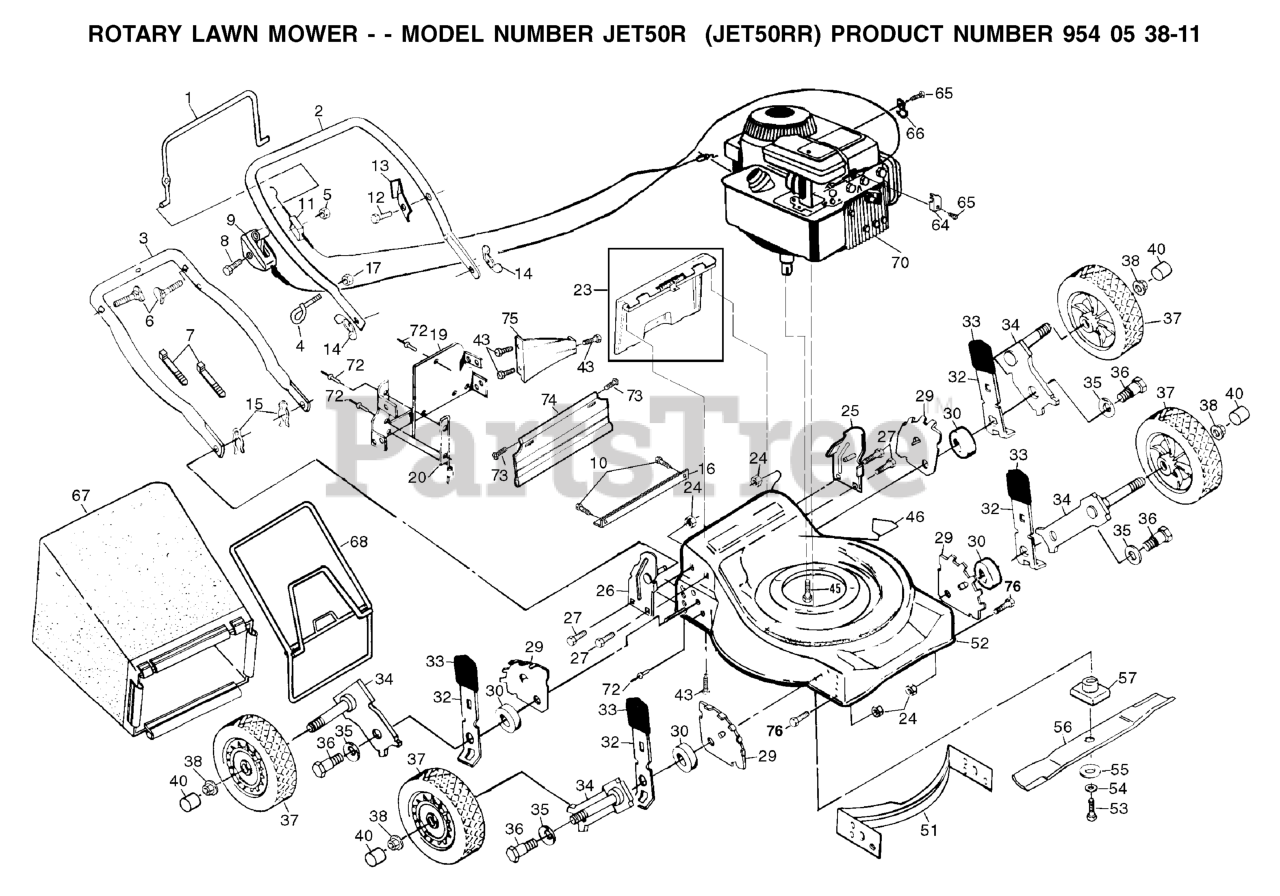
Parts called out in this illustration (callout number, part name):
1	CONTROL BAR
2	UPPER HANDLE
3	HANDLE
4	ROPE, GUIDE
5	NUT
6	HANDLE BOLT
7	TIE GUIDE
8	SCREW.PAN.HEAD
9	THROTTLE CONTROL
11	CABLE.MZR.51.RT.SP./PU.
12	TAPPING SCREW
13	BRACKET UPSTOP
14	NUT WING PM
15	HAIRPIN COTTER
16	REPL BY 532 14 61-43
17	NUT
20	SIDE BAFFLE
23	REAR DOOR ASSEMBLY KIT
24	LOCKNUT PM
25	HANDLE BRACKET ASSEMBLY - LEFT
26	HANDLE BRACKET ASSEMBLY-RIGHT
27	SELF-TAPPING SCREW 5/16-18X3/4
29	WHEEL ADJUST BRACKET
30	RP SPACER HT ADJ
32	SELECTOR SPRING
34	AXLE, REAR
35	WASHER.BELLEVILLE (3 2 LB)
36	BOLT
37	WHEEL
38	HEX FLANGE LOCKNT
45	BOLT 3/8-16X1-1/8
46	DECAL MOWER CUT/FINGER
53	SCREW, HEX HD 3/8-24 X 1-3/8
54	LOCKWASHER
55	WASHER,HARDEN
56	BLADE.20.MULCH.(50DK,6020MD)
57	BLADE ADAPTOR
64	WASHER
65	SCREW.HEX.HEAD.WASHER.10-16
66	GUIDE CLIP PM
68	CATCHER.FRAME.WALK
72	RIVET BLIND
73	HINGE SCREW
74	REAR SKIRT
76	SCREW 1/4X20
